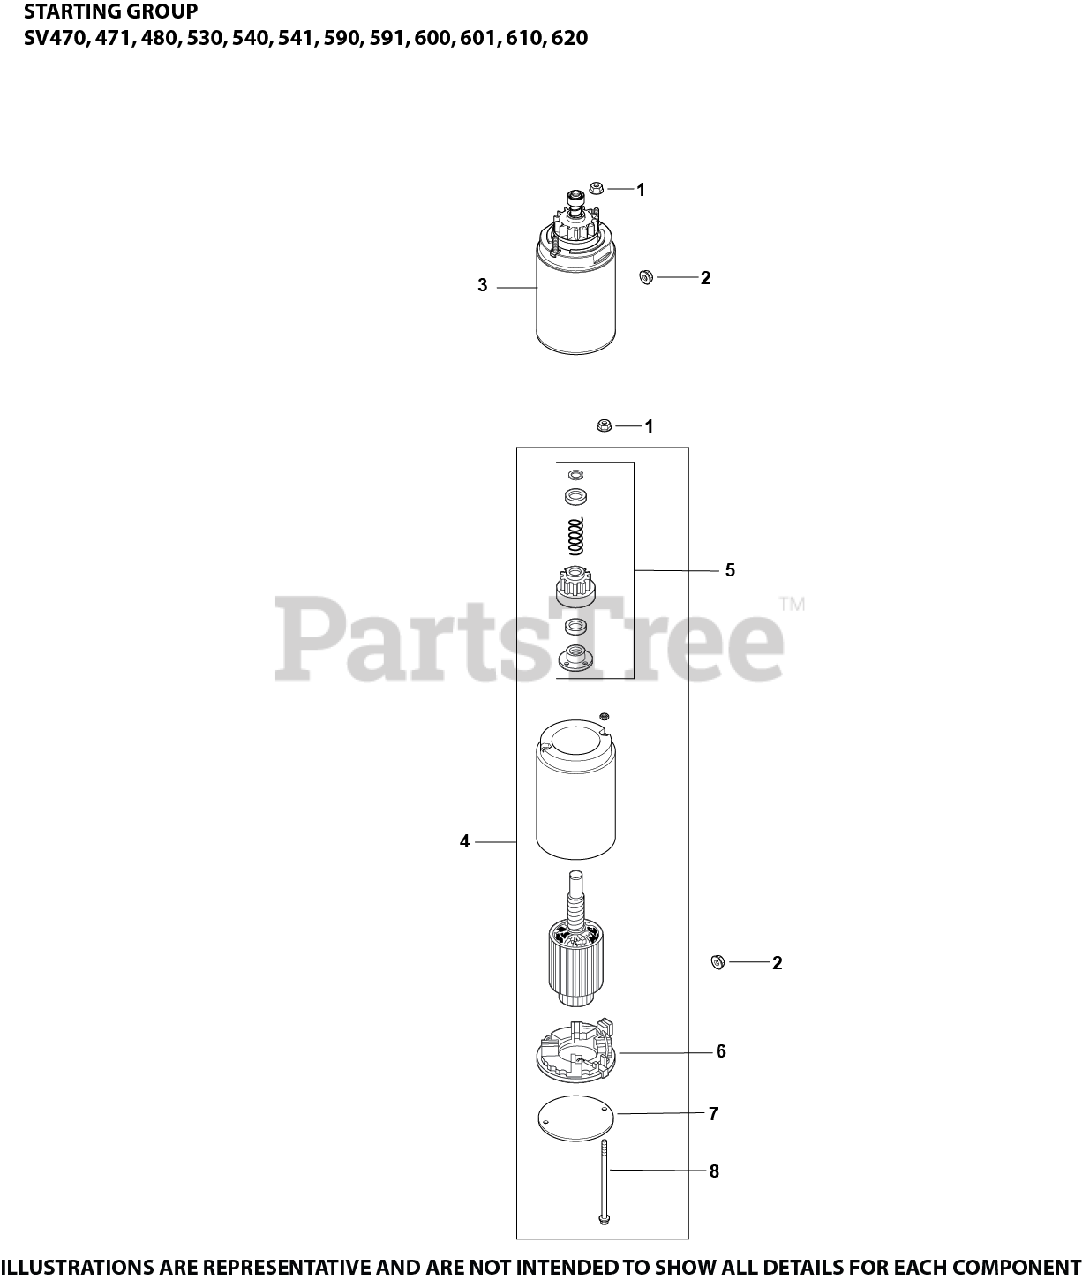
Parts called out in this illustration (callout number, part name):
1	NUT,FREE SPIN FLG #10-24-(#2510056S)
2	NUT, FLANGE 1/4-20
4	ELECTRIC STARTER-BENDIX DRIVE USE 20 098 11-S
5	KIT, DRIVE (J.E.) - (#DSC)
6	BRUSH KIT
7	CAP, DRIVE END (J.E.)
8	BOLT, THRU - DISCONTINUED
